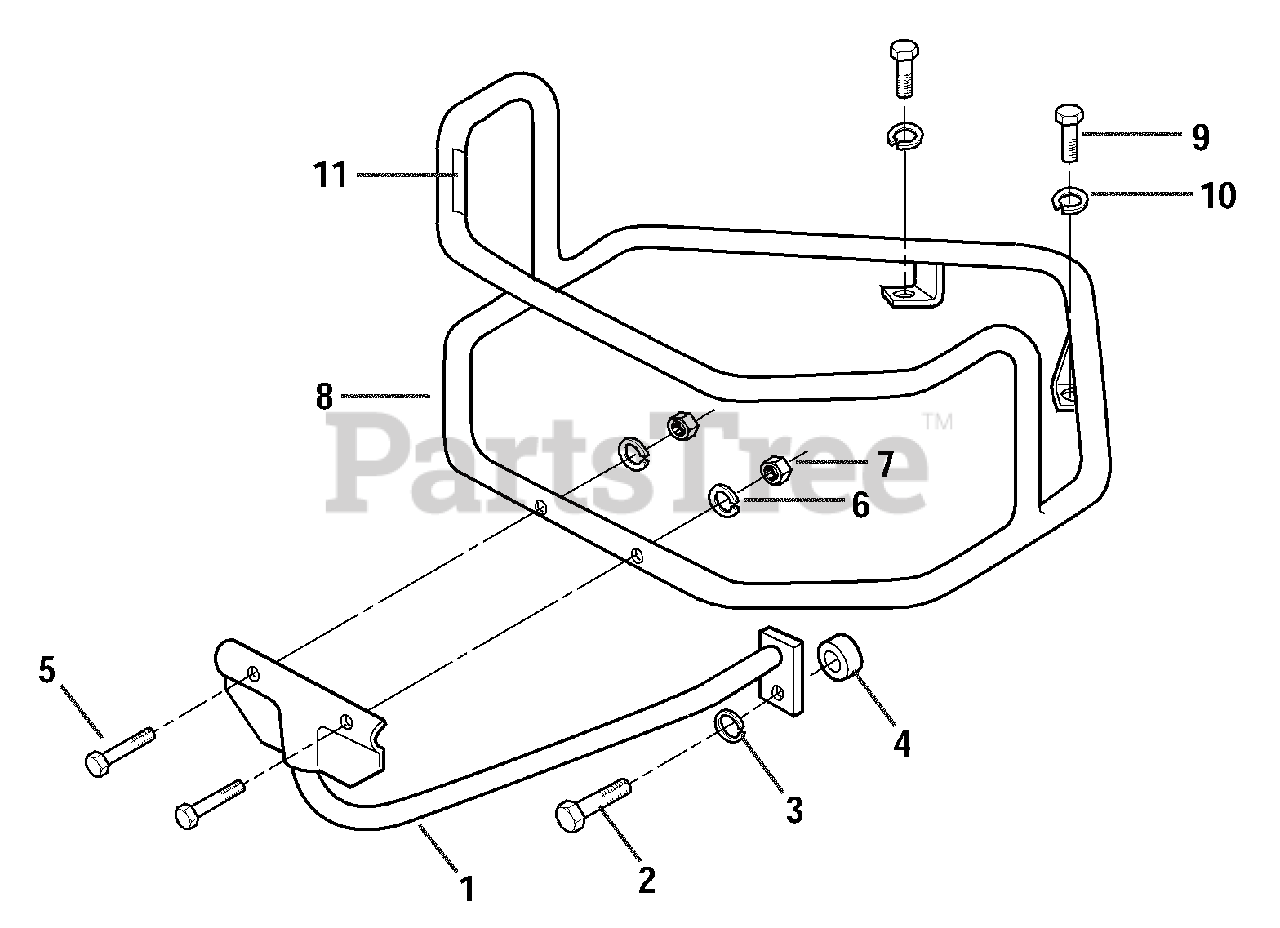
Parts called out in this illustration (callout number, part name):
1	Brace - bumper bottom
2	Bolt - hex hd., 1/2-13 x 1-1/2"
3	Lockwasher - spring lock, 1/2"
4	Spacer, 1/2"
5	Bolt - hex hd., 5/16-18 x 1-1/2"
6	Lockwasher - spring lock, 5/16"
7	Nut - hex, 5/16"-18
8	Bumper wraparound
9	Bolt - hex hd., 3/8-16 x 1"
10	Lockwasher - spring lock, 3/8"
11	Decal - for bumper
